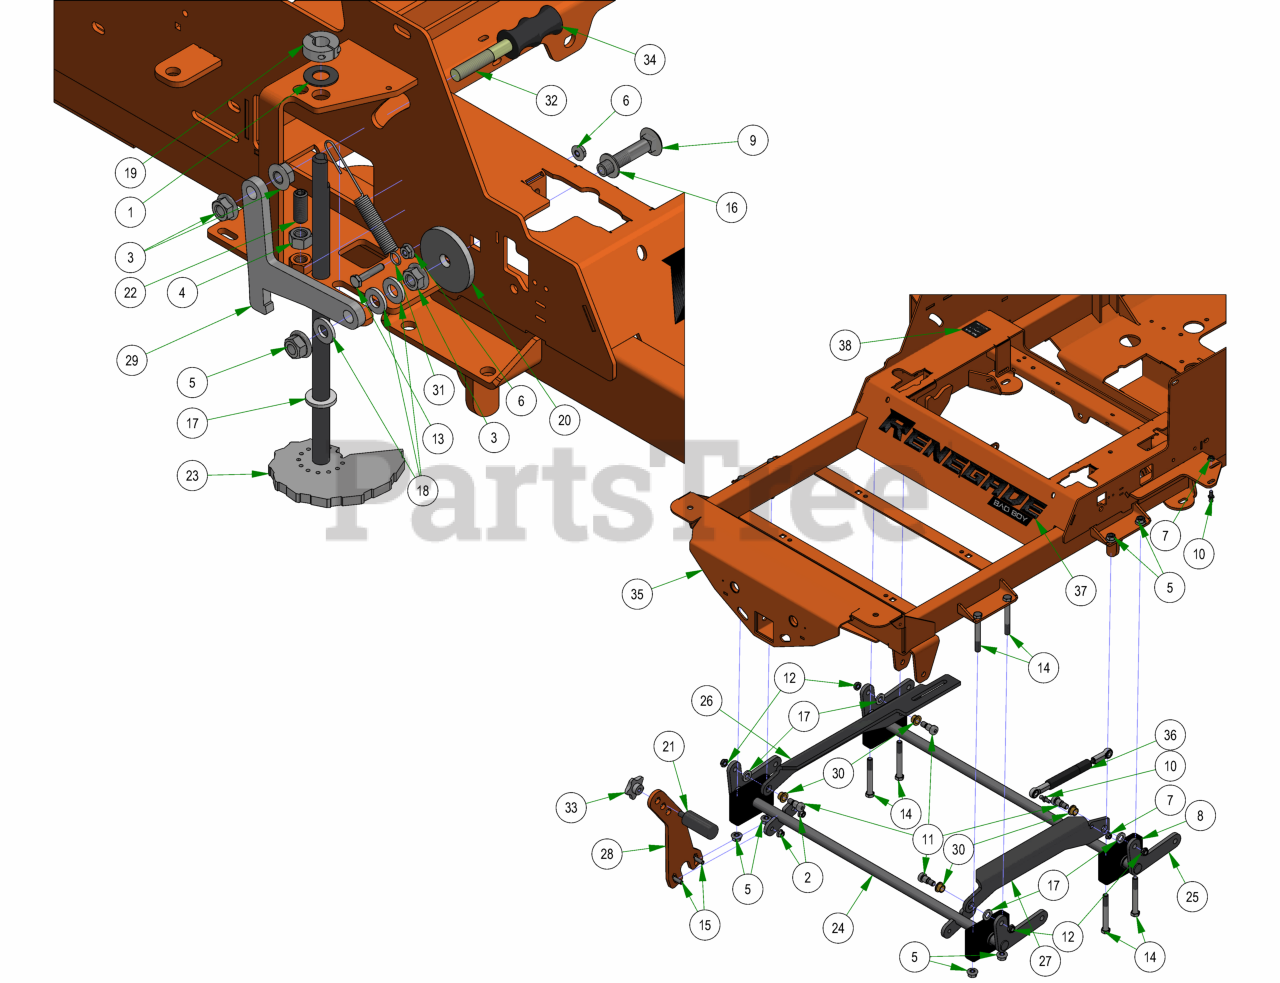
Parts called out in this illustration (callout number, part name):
1	.625 ID x 1.250 OD x .062 THK F/W Nylon
2	3/8-16 NYLON INSERT FLANGE LOCKNUT (GR.F) ZINC
3	1/2-13 HEX SERRATED FLANGE NUT HARD/ZINC
4	1/2-13 HEX NUT ZINC
5	1/2-13 NYLON INSERT FLANGE LOCKNUT ZINC
6	1/4-20 HEX SERRATED FLANGE NUT HARD/ZINC
7	5/16-18 HEX SERRATED FLANGE NUT HARD/ZINC
8	Pillow Block Assembly
9	2 1/2 x 1/2 Carriage Bolt
10	10mm Damper Ball Stud-XP Linkage
11	5/8 X 5/8 SOCKET SHOULDER BOLT ZINC YELLOW
12	1/2-13 NYLON INSERT JAM LOCKNUT ZINC
13	1/4-20 X 1-1/4 HEX CAP SCREW (GR.5) ZINC
14	1/2-13 X 4 HEX CAP SCREW (GR.8) ZINC YELLOW
15	3/8-16 X 1-1/4 CARRIAGE BOLT ZINC
16	.517 SQ WDTH ID X .937 OD X .060 THICK F/W PHOS/OIL
17	.635 ID X 1.120 OD X .140 THICK FLAT WASHER NYLON
18	.505 ID X 1.000 OD X .125 THICK FLAT WASHER NYLON
19	5/8" Split Collar
20	MZ Deck Idler Spacer
21	Knurled Pedal
22	Dial Rod Plunger
23	2019 Outlaw Gen2 Deck Height Dial Rod Assy
24	2019 Outlaw Actuator - Front
25	2019 Outlaw Actuator - Rear
26	2019 Actuator Linkage – Right – Black
27	2019 Actuator Linkage - Left - Black
28	Foot Lift Upright Lever
29	2019 Outlaw Deck Travel Lock
30	.627 ID X .753 OD X .500 LGTH X 1.000 FLG OD X .094 FLG THICK FLANGED BEARING OIL-IMPREG BRNZ
31	Brake Spring
32	Seat Bracket Pin
33	Foot Pedal Knob 1/2-13
34	Travel Lock Rubber Grip
35	2022 Horizontal Diesel Frame
36	250lb Gas Spring - 61" Deck
37	Renegade Front Cover Decal
38	2019 Deck Release Decal
